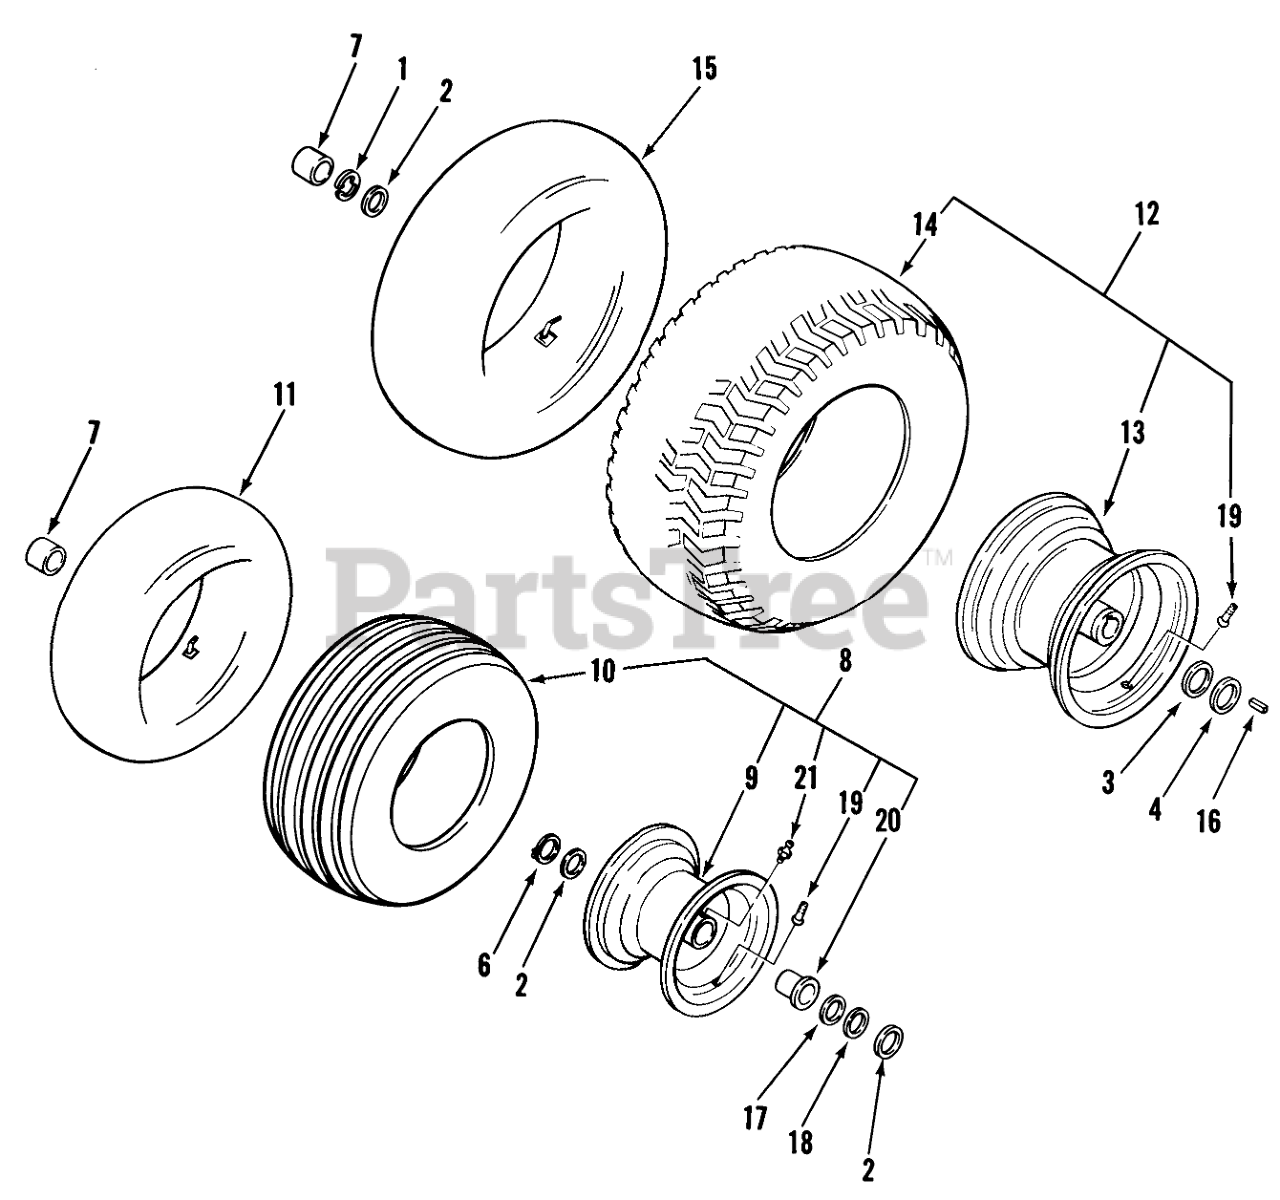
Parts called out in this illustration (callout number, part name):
1	E Ring
2	WASHER-FLAT
3	WASHER-SHIM
4	WASHER
6	Snap Ring
7	HUB CAP
8	Assy-Wheel & Tire Front 5-Speed Only
8	Assy-Wheel & Tire Front LT-832 Only
9	Front Wheel 5-Speed Only
10	Front Tire 13 x 6.50-6-5-Speed Only
10	Tire-Front 13 X 5.00-6
11	Tube (Service Only)
11	Front Tube-Service Only
12	Assy-Wheel & Tire Rear LT-1137 Only
12	Assy-Wheel & Tire-Rear 5-Speed Only
12	Assy-Wheel & Tire-Rear LT-832 Only
13	Rear Wheel LT-1137 Only
13	Rear Wheel 5-Speed Only
13	Rear Wheel LT-832 Only
14	Rear Tire 20 x 10.0-10.0
14	TIRE 18 X 9.50-8
14	TIRE
15	Tube-Inner
15	Rear Tube-Service Only
16	SQ KEY
17	WASHER
18	WASHER-SHIM
19	VALVE
20	FLANGE BEARING
21	Zerk
